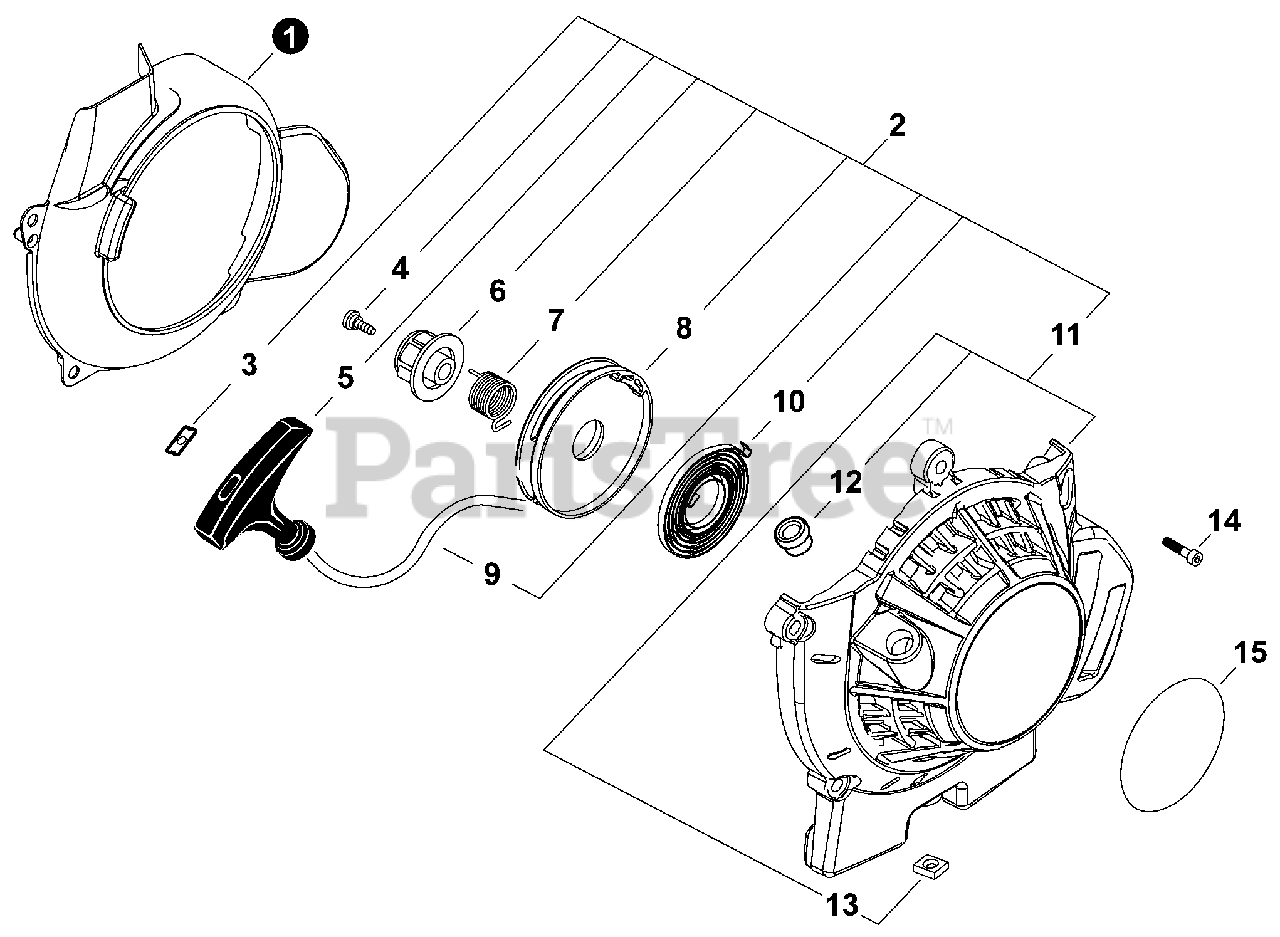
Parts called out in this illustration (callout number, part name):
1	COVER, FAN
2	STARTER ASSY, RECOIL
3	RETAINER, ROPE
5	GRIP, STARTER
7	SPRING, TORSION
8	REEL, ROPE
9	ROPE, STARTER
10	SPRING, RECOIL
11	CASE, STARTER
12	GUIDE, ROPE
13	NUT M5
14	BOLT, TORX 5x20
15	LABEL - RECOIL STARTER
